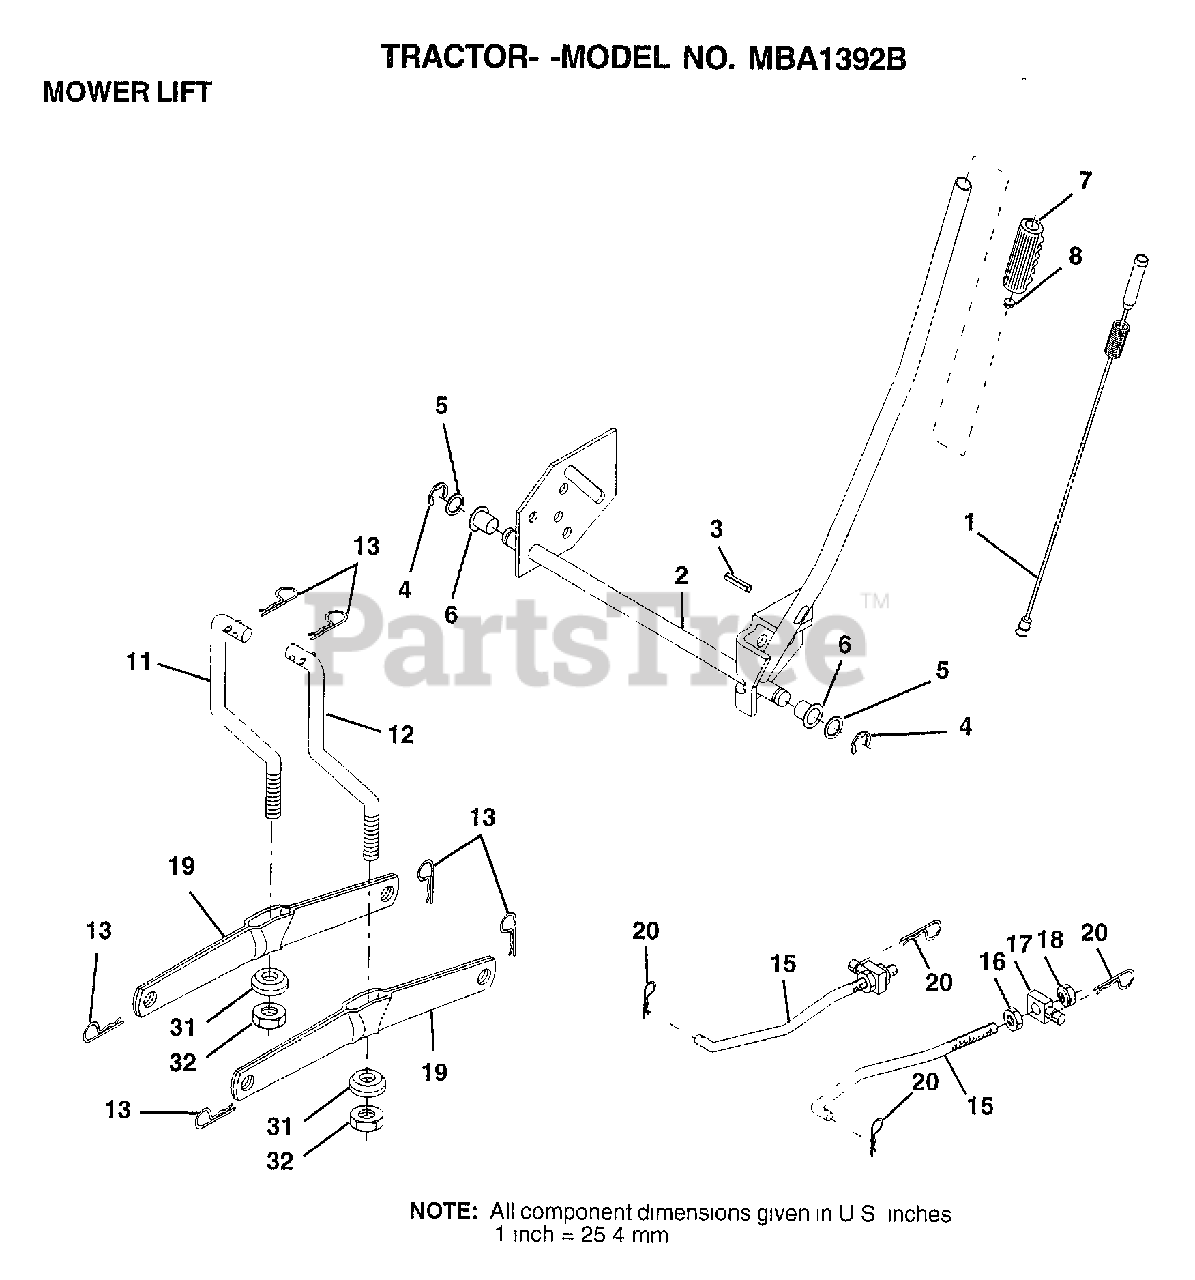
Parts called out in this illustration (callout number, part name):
1	WIRE ASM W.SPRING
2	"SHAFT ASM LIFT,RH"
3	PIN-GROOVE LT
5	WASHER
6	NYLON BEARING
7	GRIP
11	LINK.LIFT.LH.CRD
12	LINK.LIFT.RH.CRD
15	LINK, FRONT
16	NUT
17	TRUNION
18	NUT.LK.W/WSH.1/2.
19	ARM SUSP REAR
20	RETAINER SPRING
31	BEARING PVT LH
32	NUT.CROWNLOCK.3/8
